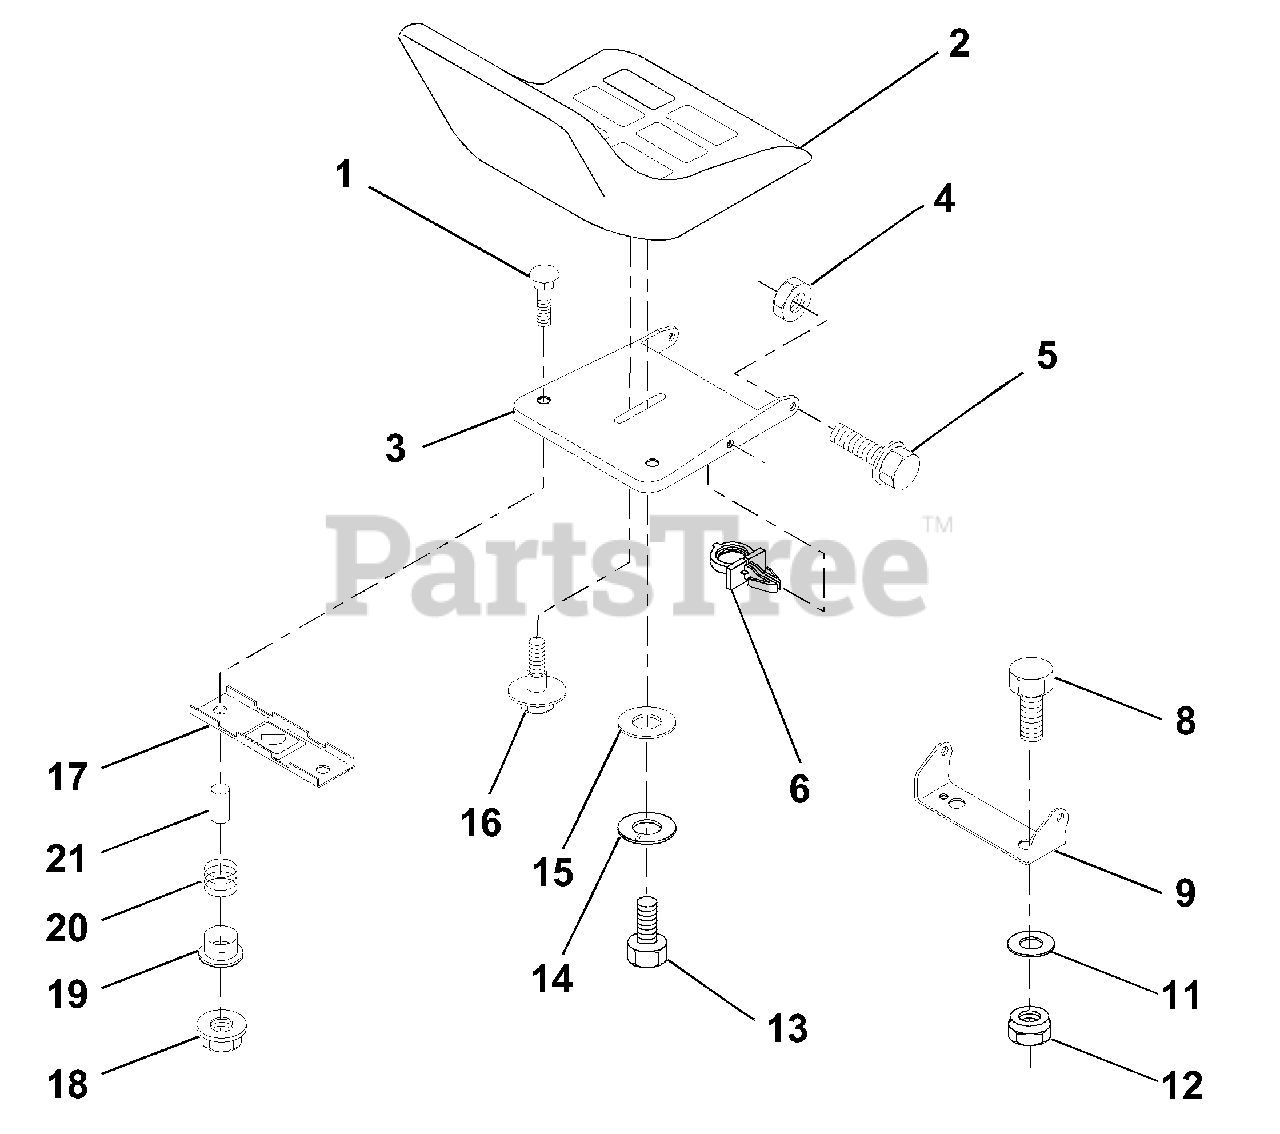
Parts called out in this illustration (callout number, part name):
1	Bolt, Carriage 1/4-20 x 1-1/2
2	Seat
3	Pan, Seat
4	Locknut, Hex w/Ins 5/16-18
5	Bolt, Shoulder 5/16-18 UNC
6	Clip, Push-in
8	Bolt, Fin Hex 3/8-16 UNC x 1
9	Bracket, Pivot Seat
11	Washer 12/32 x 2 x 10 Ga.
12	Nut, Lock Hex w/Wsh 3/8-16
13	Bolt Hex 1/2-13 x 7/8
14	Washer Lock Hvy. Hlicl Spring 1/2
15	Washer, 17/32 x 1-3/16 x 12 Ga.
16	Bolt, Shoulder
17	Bracket, Switch, Mounting
18	Nut, Hex Large Flange Lock
19	Bushing, Snap
20	Spring, Compression
21	Spacer, Split 28 Id. x .88 Lg.
